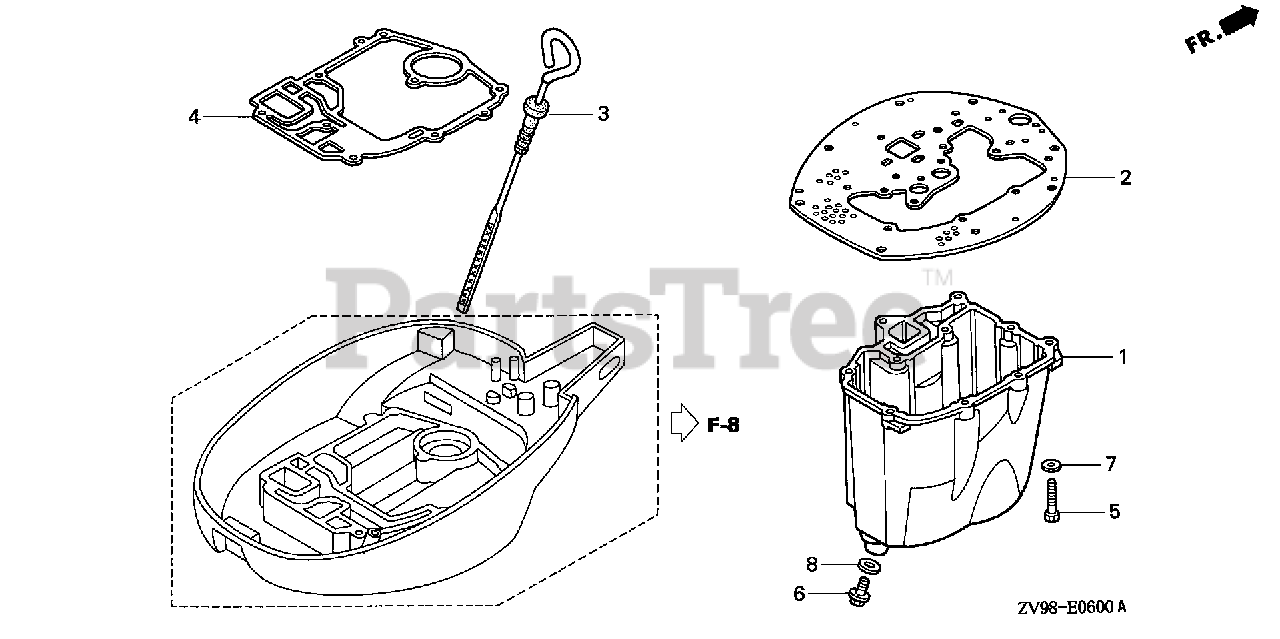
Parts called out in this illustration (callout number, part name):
1	PAN, OIL *TGRAY* (GRAY)
2	GASKET, OIL PAN
3	DIPSTICK, OIL
4	GASKET, ENGINE CASE (LOWER)
5	BOLT, HEX. (6X25)
6	BOLT, DRAIN PLUG
7	WASHER, PLAIN (6MM)
8	WASHER, DRAIN PLUG (12MM)
